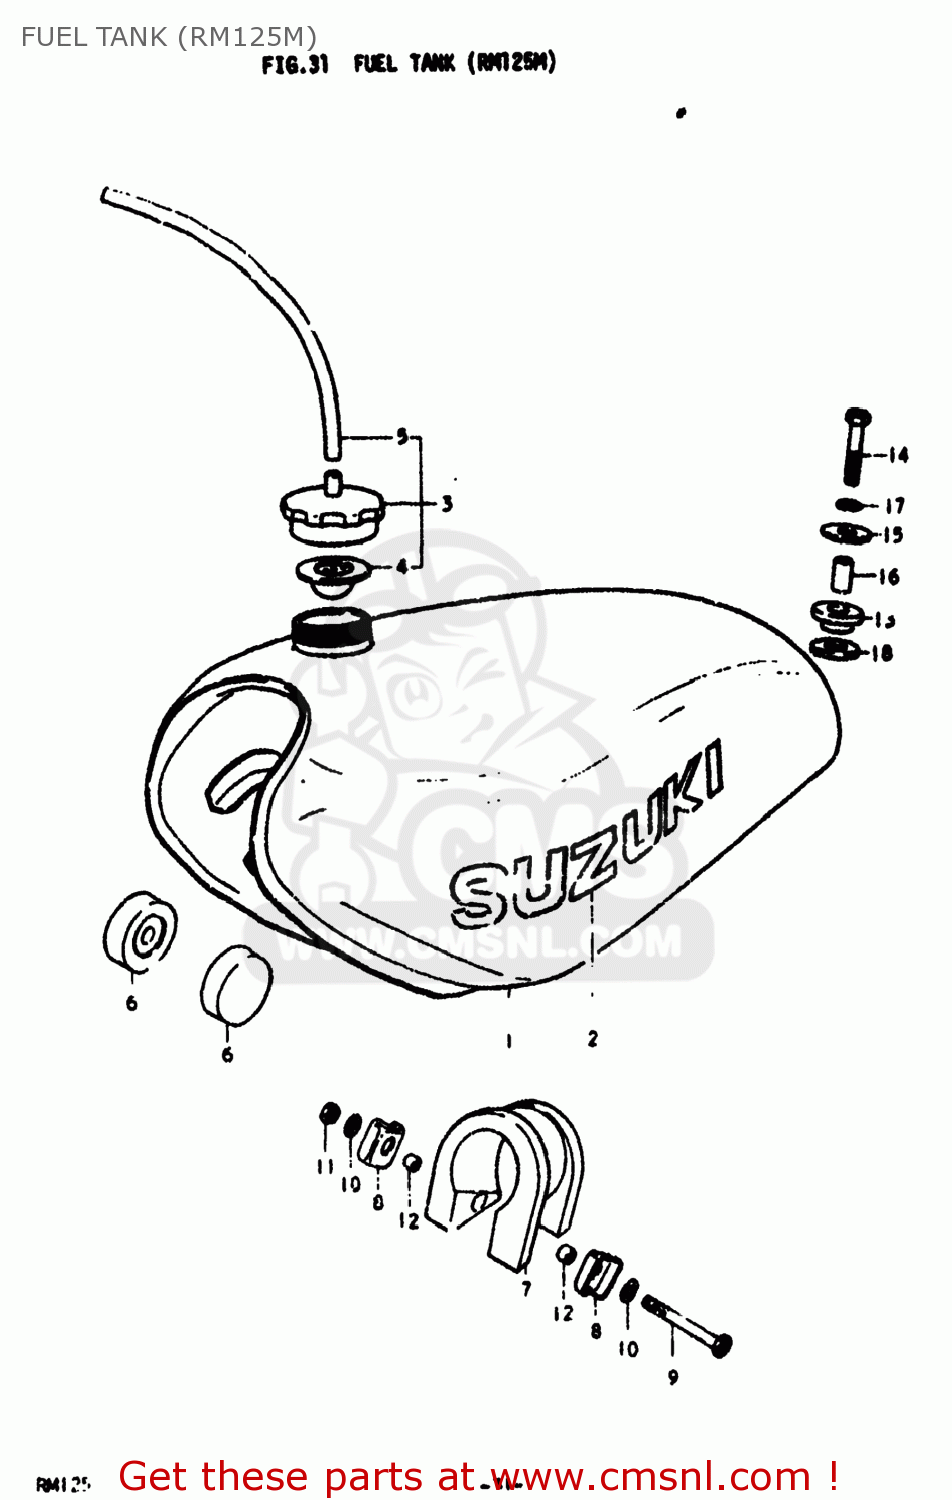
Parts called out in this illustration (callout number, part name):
1	TANK ASSEMBLY,FUEL
2	EMBLEM
3	CAP ASSY,FUEL TANK FILLER
4	GASKET,FUEL TANK CAP (NAS)
5	HOSE
6	CUSHION
7	CUSHION,FUEL TANK,REAR
8	CLIP
9	BOLT
10	WASHER 6MM
11	NUT
12	SPACER (6.1X8X5.2)
13	CUSHION
14	WASHER
15	WASHER
16	SPACER
17	WASHER,LOCK
18	CUSHION
